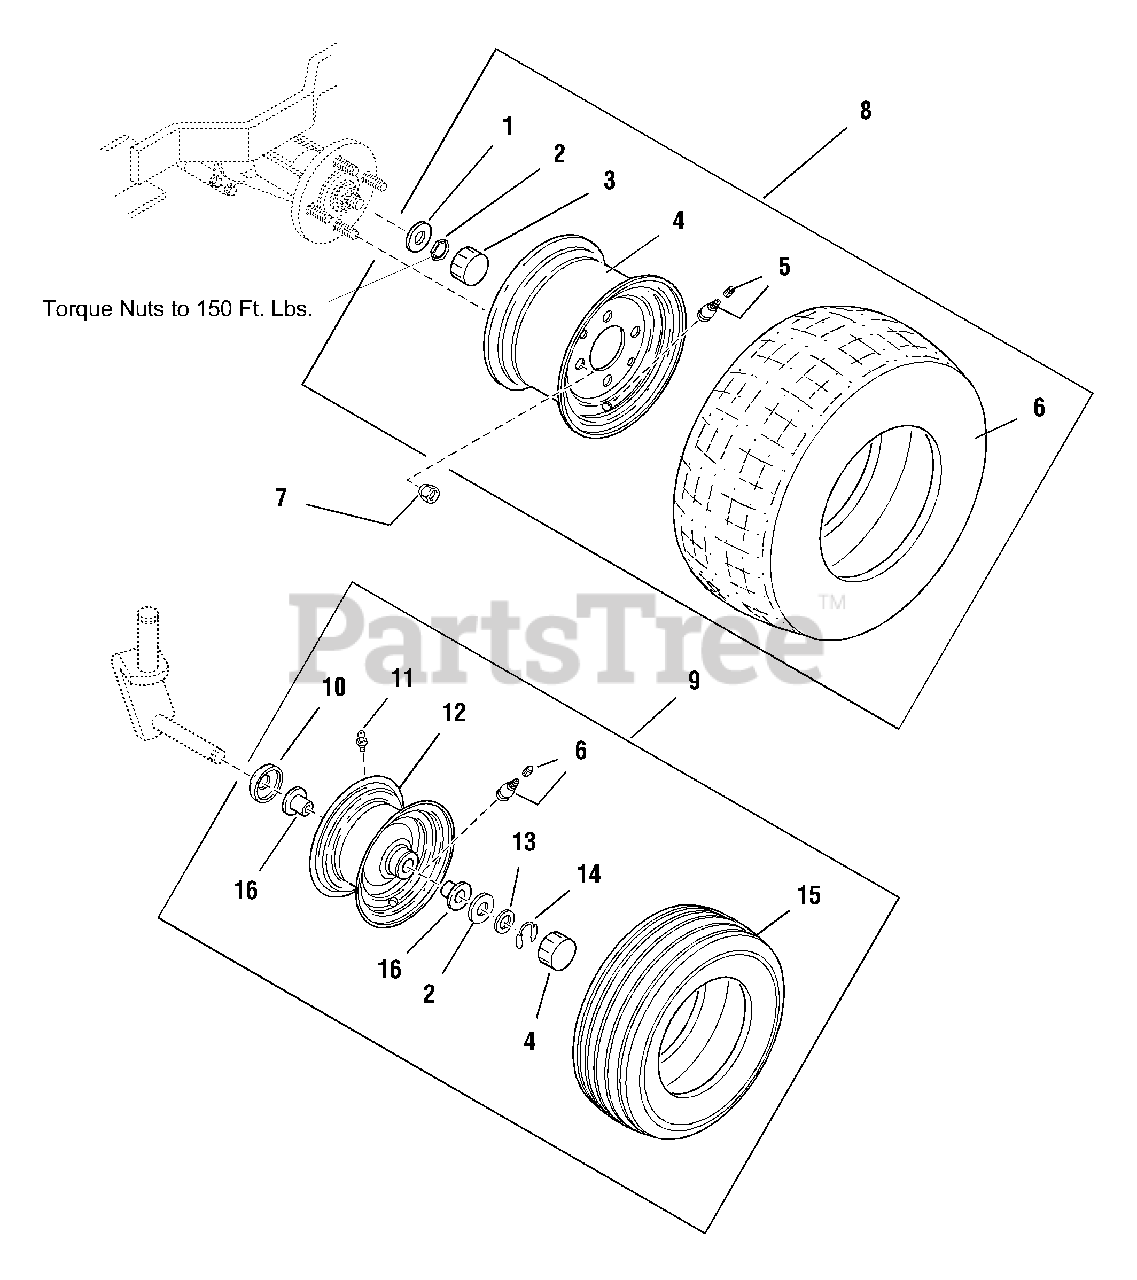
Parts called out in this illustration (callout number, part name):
2	NUT, Hex Lock Pal, 3/4-20
4	REAR WHEEL ASSEMBLY
5	VALVE STEM & CAP
6	TIRE, 18 x 8.50-8
8	WHEEL & TIRE ASSEMBLY, Rear, 18 x 8.50-8
9	WHEEL & TIRE ASSEMBLY, Front, 13 x 5.00-6
10	WASHER, Cupped
11	FITTING, Lube
12	FRONT WHEEL ASSEMBLY
13	WASHER
14	RING, Klip, .750
15	TIRE, Front Rib Tread, 13 x 5.00-6
16	BUSHING, Wheel
